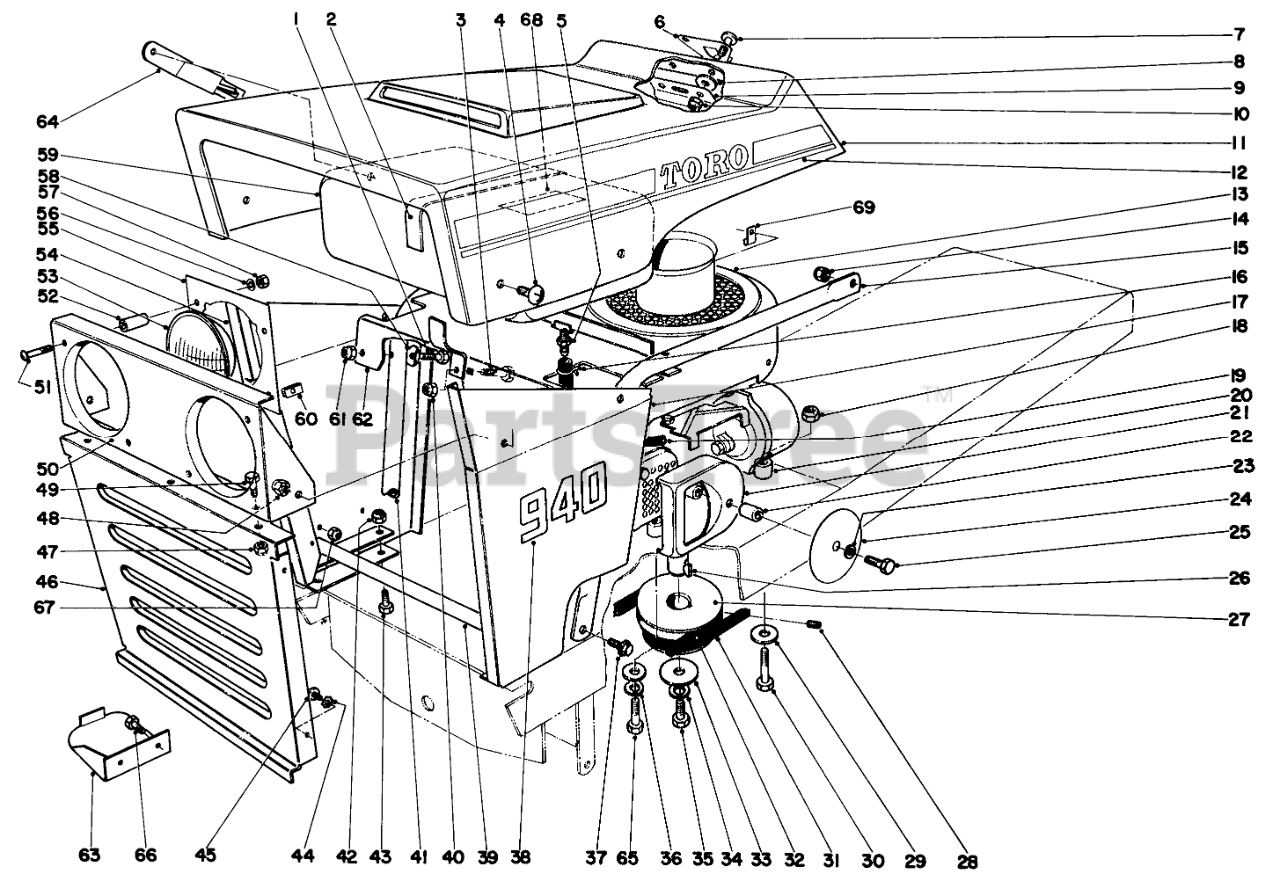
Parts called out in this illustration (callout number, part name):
1	SCREW-HH
2	Strap Gas Tank
3	SCREW-HH
4	Screw
5	Hose Connector
6	Hood Clip
8	WASHER-FLAT
9	Hood Latch
12	Decal Hood Left
13	Engine
14	Nut
15	Support Gas Tank Left
16	CLAMP-HOSE
17	Skin Left Front
18	Nut
20	Spacer
21	Baffle Muffler
22	Spacer Muffler
23	WASHER-LOCK/SP
24	Shield Baffle
25	SCREW-HH
26	KEY-WOODRUFF
27	Pulley Engine
28	SCREW-SET, HSH
29	WASHER-FLAT
30	SCREW-HH
31	Belt
32	V BELT PTO
33	WASHER-FLAT
34	Lockwasher
35	SCREW-HH
36	WASHER-LOCK
38	Decal 940
39	Hinge
41	Support Gas Tank Right
43	SCREW-HH
44	WASHER-LOCK, EXT
46	Grille
48	Nut
49	SCREW-HH
50	Headlamp Panel
51	Round Head Pan Screw
52	Spacer
53	HEAD LAMP
54	Skin Right Front
55	Headlight Holder
56	WASHER-LOCK/SP
57	NUT-HEX
58	WASHER
59	Gas Tank
60	NUT-CLIP,U
62	Bracket Gas Tank
63	Trimmer Support
64	Bracket Trimmer
65	SCREW-HH
66	SCREW-HH
67	NUT-LOCK, CONE
68	Decal
